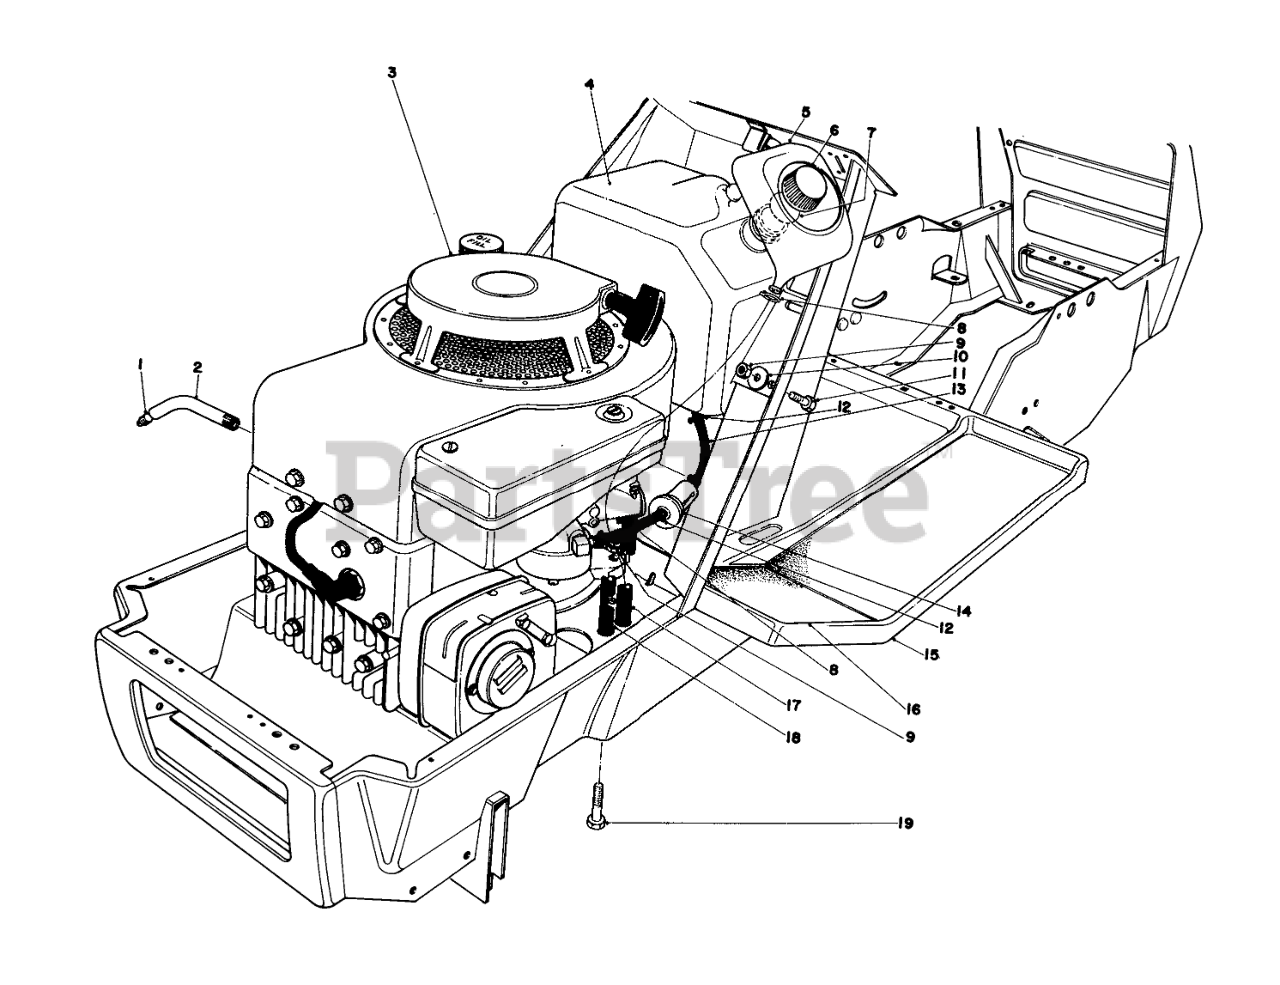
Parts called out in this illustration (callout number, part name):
1	PLUG-PIPE, SQH
2	OIL DRAIN TUBE
3	Engine
4	Gas Tank (Incl. Ref. #5)
5	Funnel-Overflow
6	Gas Cap (Incl. Ref. #7)
7	Gasket Gas Cap
8	HOSE CLAMP
9	NUT-LOCK, CONE
10	WASHER
11	SCREW-HH
12	CLAMP-HOSE
13	GAS HOSE
14	FUEL FILTER
15	Frame
16	LH FOOT TREAD
17	FUNNEL HOSE
18	CARB DRAIN HOSE
19	SCREW-HH
